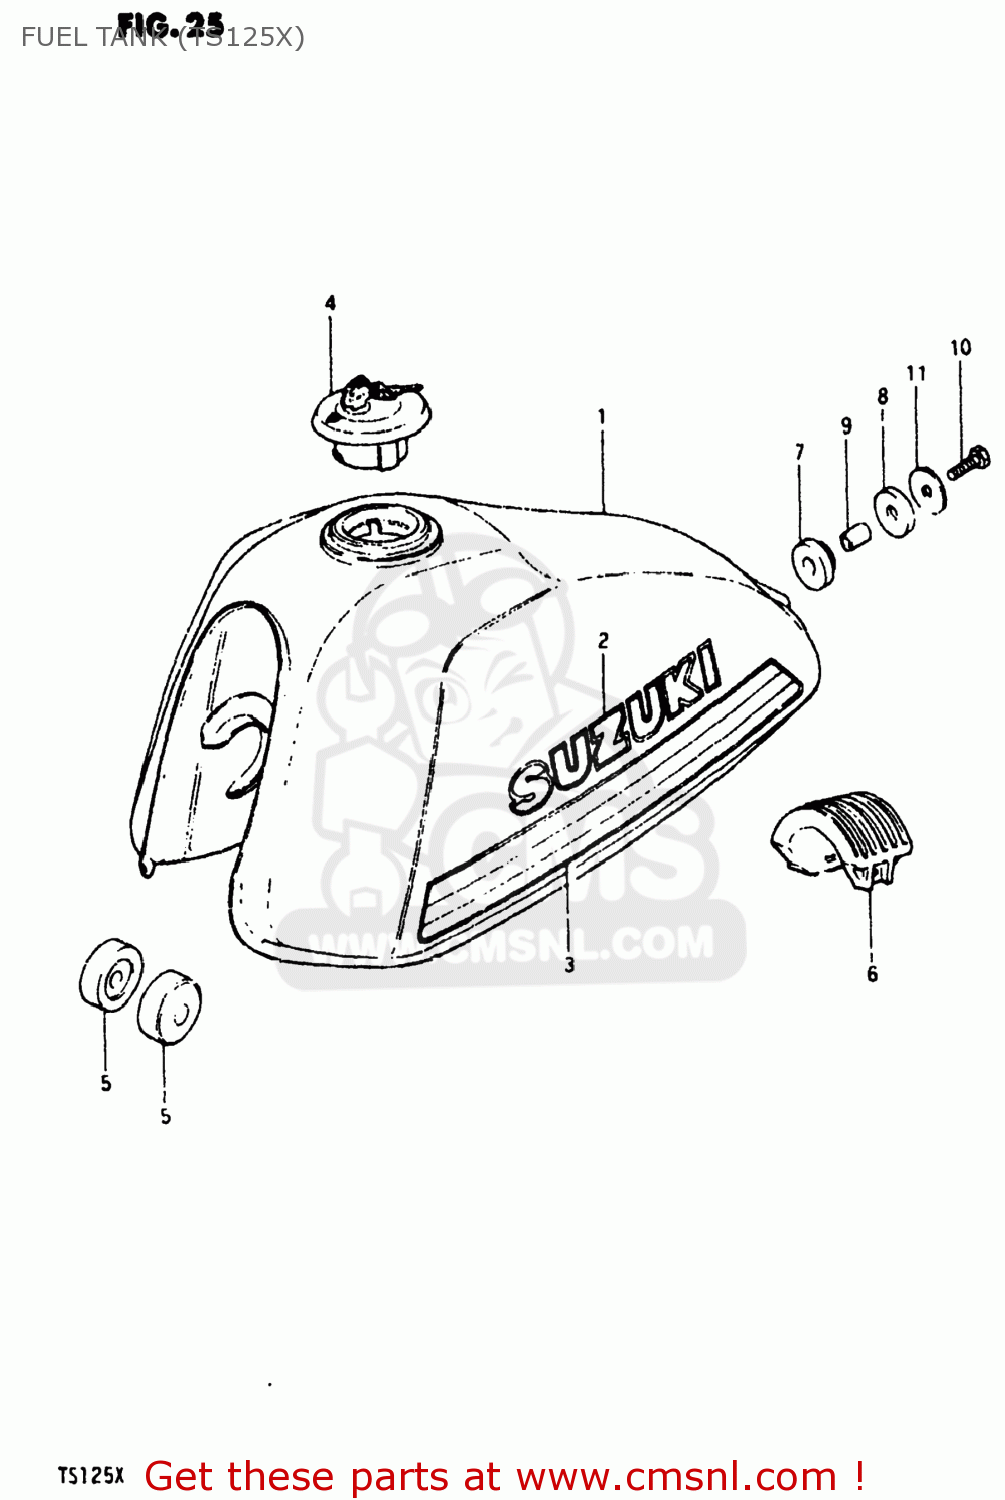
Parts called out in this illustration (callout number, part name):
1	TANK ASSEMBLY,FUEL
2	EMBLEM,FUEL TANK
3	TAPE SET,FUEL TANK
4	CAP SET,FUEL TANK
5	CUSHION
6	CUSHION,FUEL TANK
7	CUSHION
8	CUSHION
9	SPACER(8.5X12X19)
10	BOLT (8X30)
11	WASHER (8.5X29X1.6)
